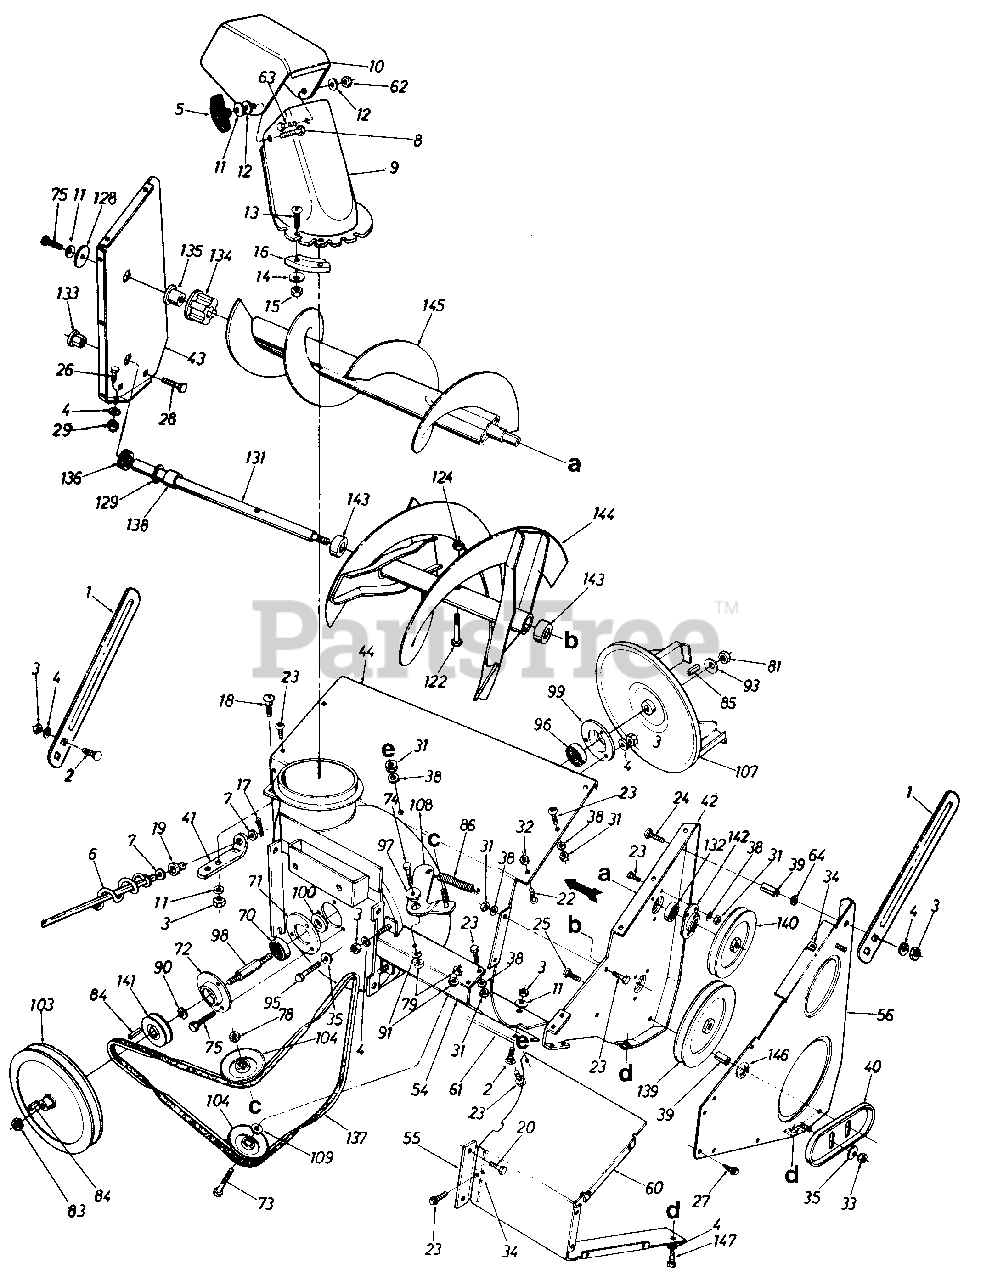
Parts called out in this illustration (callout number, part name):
2	Carriage Bolt 5/16-18 x .62"
3	Hex Nut 5/16-18 Thd.
4	L-Wash. 5/16" I.D.
5	Hand Knob Ass'y.
6	Chute Crank Ass'y.
7	Fl-Wash. .385" I.D. x .62"
8	Carriage Bolt 5/16-18 x 1.0"
9	6" Dia. Lower Chute
10	6" Dia. Upper Chute
11	Bell-Wash. .345" I.D. x .88" O.D. x .06"
12	Fl-Wash. .344" I.D. x .125" O.D. x .125"
13	Truss Mach. Scr. 1/4-20 x .75" Lg.
14	Fl-Wash. 1/4" I.D.
15	Hex L-Nut 1/4-20 Thd.
16	Chute Flange Keeper
17	Cotter Pin
18	Carriage Bolt 5/16-18 x .75"
19	Bushing
20	Hex Self-Tap Scr. 5/16-24 x .5" Lg.
22	Truss Mach. Scr. 1/4-20 x .5"
23	Hex Bolt 1/4-20 x .5" Lg.
24	Carriage Bolt 5/16-18 x 1.75
25	Hex Bolt 3/8-16 x 2.0"
26	Hex Bolt 5/16-18 x .75" Lg.
27	Hex Self-Tap Scr. 1/4-20 x .38" Lg.
28	Carriage Bolt 3/8-16 x .75"
29	Hex Nut 5/16-18 Thd.
31	Hex Nut 1/4-20 Thd.
32	Hex Ins. L-Nut 1/4-20 Thd.
33	Hex Jam Nut 3/8-16 Thd.
34	Speed Clip
35	Bell-Wash. 3/8" I.D.
38	L-Wash. 1/4" I.D.
39	Spacer .375" I.D. x 1" Lg.
40	Slide Shoe
42	Spiral Housing Plate R.H.
43	Spiral Housing Plate L.H.
44	24" Spiral Hsg. Ass'y.
54	V-Channel
55	Support Bracket
56	Side Cover Ass'y.
60	Belt Cover 6.42"
63	Truss Mach. Scr. 5/16-18 x .75"
64	Push Speed Nut
70	Ball Bearing
71	Spindle Reinforcement Plate
72	Open Brg. Housing
73	Hex Bolt 3/8-24 x 1.5" Lg.
74	Hex Bolt 3/8-24 x 1.25" Lg.
75	Hex Bolt 5/16-18 x 1" Lg. (Grade 5)
78	Hex Ins. L-Nut 3/8-24
79	Hex Nut 3/8-24 Thd.
81	Hex Jam Nut 5/8-18 Thd.
83	Hex L-Nut 5/8-18 Thd.
84	Sq. Key 3/16" x .75"
85	Sq. Key 3/16" x 1.5"
86	Ext. Spring 3/4" O.D. x 4" Lg.
90	Fl-Wash. 635" I.D.
91	L-Wash. 3/8" I.D.
93	Bell-Wash. .630" I.D.
95	Shld. Bolt .50" Dia. x 2.11" Lg.
96	Ball Bearing
97	Shld. Spacer .625 I.D.
98	Fan Spindle
99	Bearing Hsg. Ass'y.
100	Spacer.790" I.D.
103	5/8 V-Pulley 7.5" O.D.
104	V-Idler Pulley 3.5" O.D.
107	11" Dia. Blower Fan Ass'y.
108	Idler Bracket Ass'y.
109	Fl-Wash..40" I.D.
122	Shear Bolt 5/16-18 x 1.5"
124	Hex Ins. L-Nut 5/16-18 Thd.
128	Flat Washer .32" I.D.
129	Fl-Wash. .76" I.D.
131	Spindle Shaft
132	Ball Brg. .62" I.D.
133	Hex Flange Brg.
134	Tubing Support Brg.
135	Shaft Pin
136	Spacer 1.25" I.D. x 1.5
137	V-Belt
138	Spacer
139	1/2 V-Pulley 9" O.D.
140	1/2 V-Pulley 5.5" O.D.
141	1/2 V-Pulley 2.75"
142	Bearing Housing
143	Sleeve Brg. .75" I.D.
144	10" Spiral Ass'y. R.H.
145	24" Auger Ass'y.
146	Push Nut Bolt Retainer
147	Hex Wash. AB-Tap Scr. 5/16-18 x.75" Lg.
05139A-0637	BLADE-GUIDE (DRIFT - POWDER BLACK (0637)
05139A-0638	BLADE-GUIDE (DRIFT - MTD/TROY-BILT RED (0638)
05139A-0662	BLADE-GUIDE (DRIFT - OYSTER GRAY (0662)
05139A-0665	BLADE-GUIDE (DRIFT - YARDMAN GREEN (0665)
05139A-0674	BLADE-GUIDE (DRIFT - YARDMAN YELLOW (0674)
05139A-0716	BLADE-GUIDE (DRIFT - CUB YELLOW-99 (0716)
